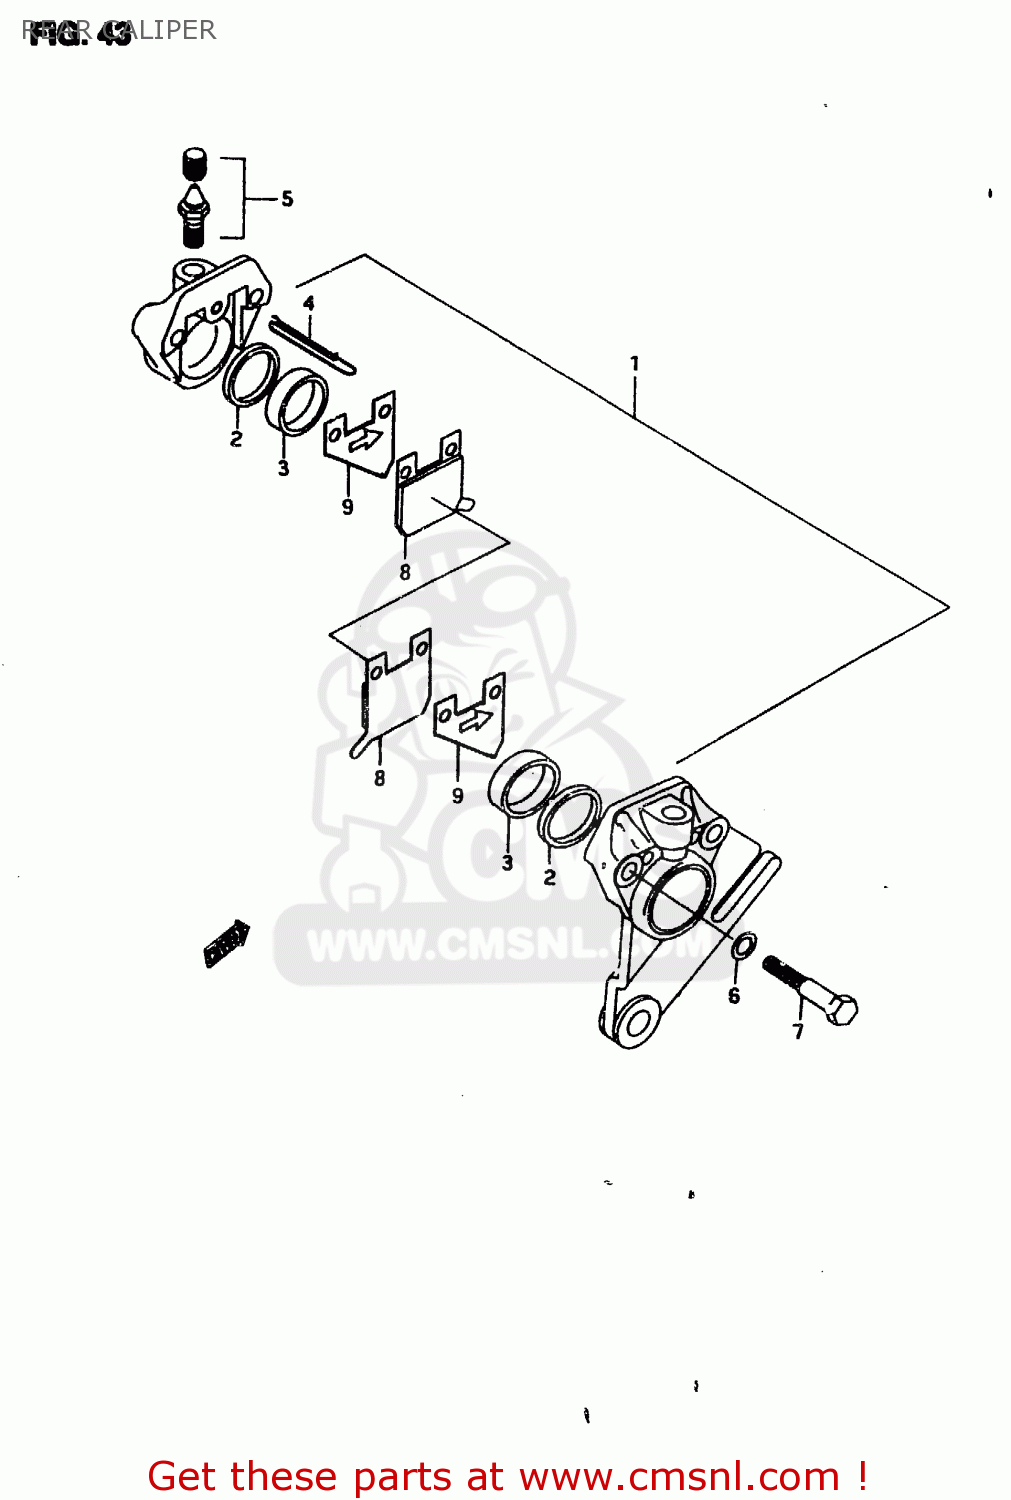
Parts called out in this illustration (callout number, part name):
1	PISTON SET
2	OIL SEAL
3	PISTON
4	SPRING,PAD
5	BLEEDER
6	WASHER
7	BOLT
8	PAD SET
9	SHIM,PAD
